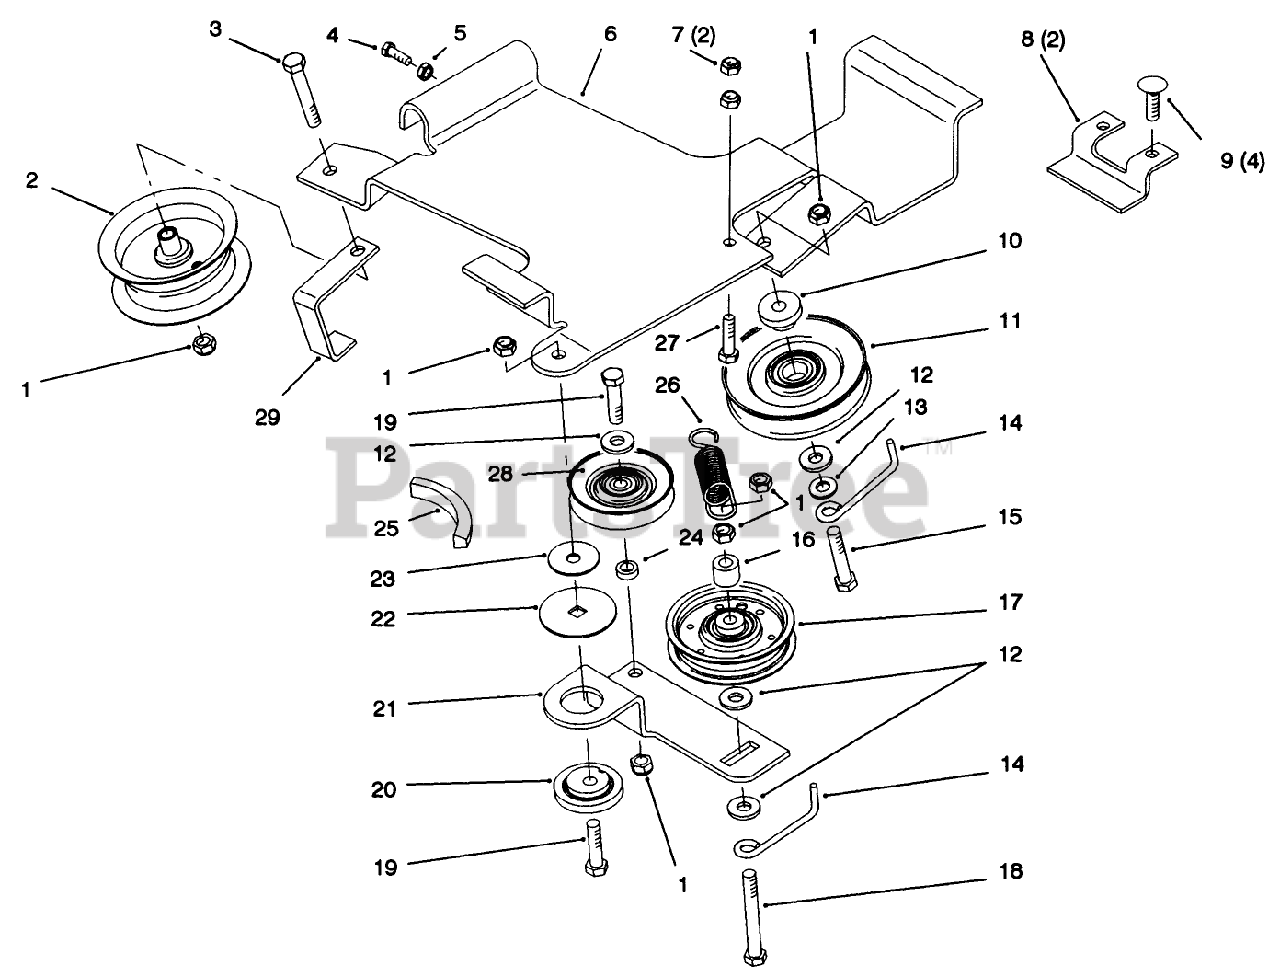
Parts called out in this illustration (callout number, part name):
1	NUT-LOCK, NI
2	IDLER
3	SCREW-HH
4	SCREW-HEX HD
5	NUT-JAM
6	RACK-TILLER DRIVE
7	NUT-LOCK, NI
8	BRACKET - RACK MOUNTING
9	BOLT-CARR
10	SPACER
11	PULLEY-IDLER
12	WASHER-SPACER
13	WASHER-FLAT
14	GUIDE-BELT
15	SCREW-HH
16	Spacer-Pivot
17	PULLEY-IDLER, FLAT
18	SCREW-HH
19	SCREW-HH
20	BUSHING
21	ARM-IDLER
22	WASHER-BEARING
23	WASHER
24	SPACER
25	V-BELT (A, 148.50" )
26	SPRING-EXTENSION
27	SCREW-HH
28	PULLEY-IDLER
29	GUIDE-BELT
